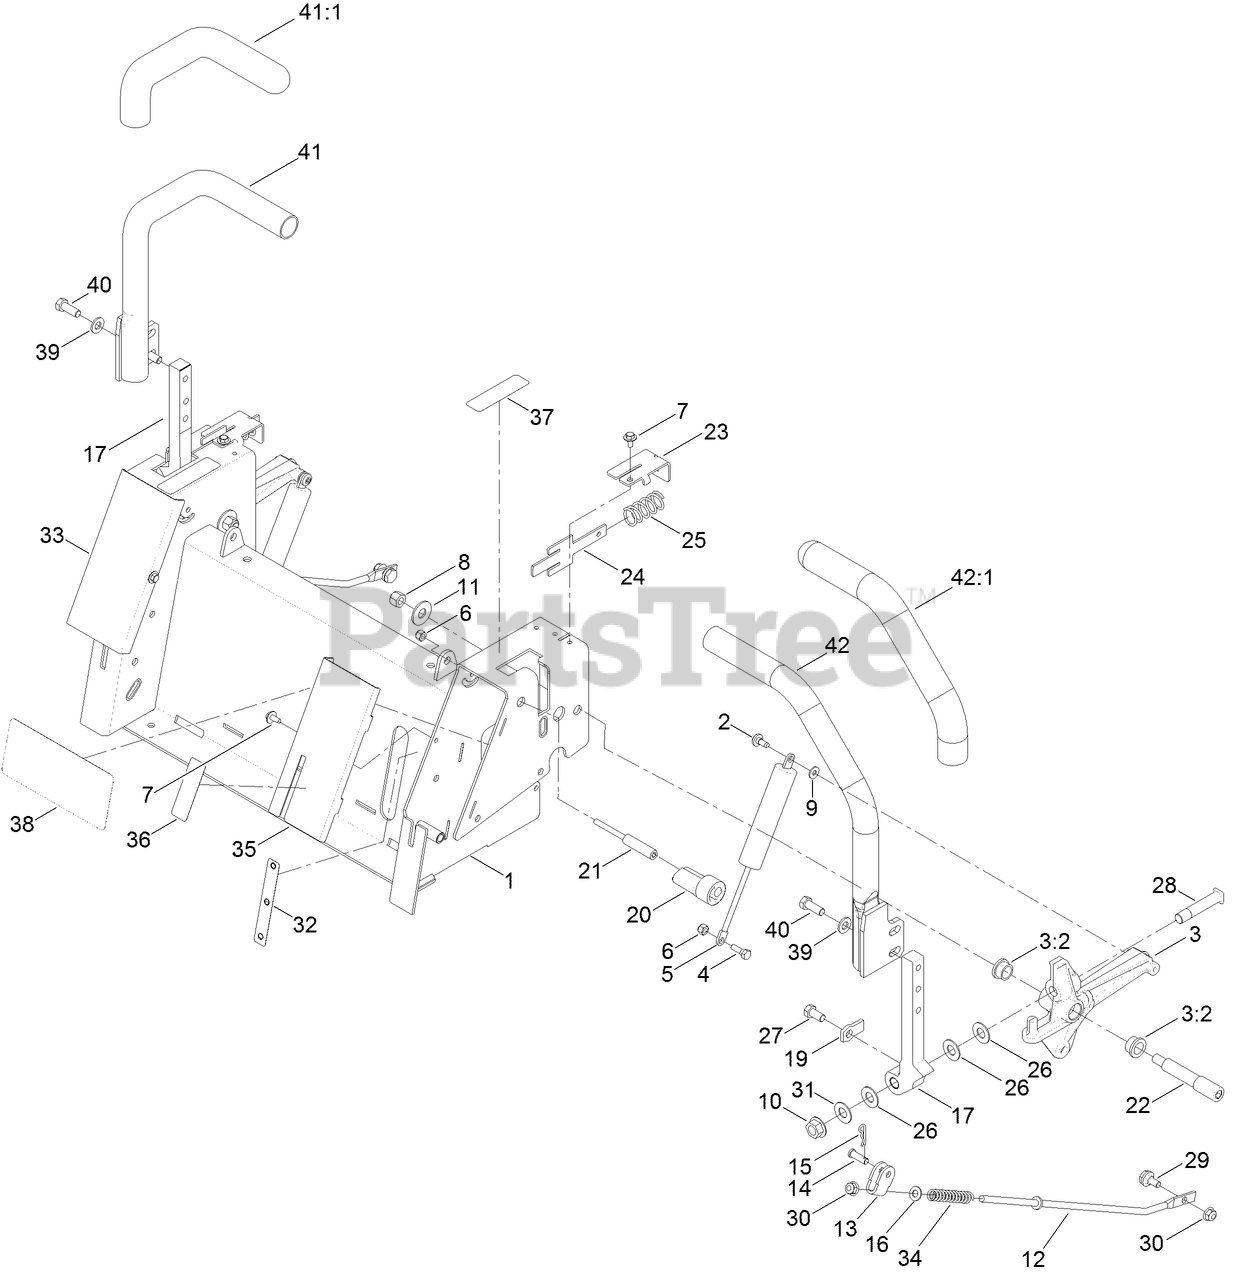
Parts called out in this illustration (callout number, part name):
1	BOX-CONTROL
2	SCREW-SHOULDER
3	ACTIVATOR ARM ASM
3:2	BUSHING
4	BOLT-SHOULDER
5	DAMPER
6	NUT-LOCK, NI
7	SCREW-HHFTF
8	NUT-LOCK, NI
9	WASHER
10	NUT-HF
11	WASHER-FLAT
12	ROD-CONTROL
13	BRACKET-CONTROL
14	PIN-CLEVIS
15	PIN-COTTER
16	WASHER-PLAIN
17	ARM-ACTUATOR
19	TAB-STOP
20	ECCENTRIC
21	SCREW-ECCENTRIC
22	BOLT-SHOULDER
23	BRACKET-RETURN
24	PLATE-RETURN
25	SPRING-COMPRESSION
26	WASHER-PIVOT
27	SCREW-HH
28	BOLT-SHOULDER
29	BOLT-SHOULDER,HFH
30	NUT-HF, NI
31	WASHER-TEFLON
32	DECAL-FILL, FUEL
33	COVER-CONTROL, RH
34	SPRING-RETURN, NEUTRAL
35	COVER-CONTROL, LH
36	DECAL-BRAKE, PARKING
37	DECAL-CONTROL, MOTION
39	WASHER-FLAT
40	SCREW-HH
41	RH LEVER/GRIP ASM
41:1	GRIP-CONTROL, MOTION
42	LH LEVER/GRIP ASM
42:1	GRIP-CONTROL, MOTION
